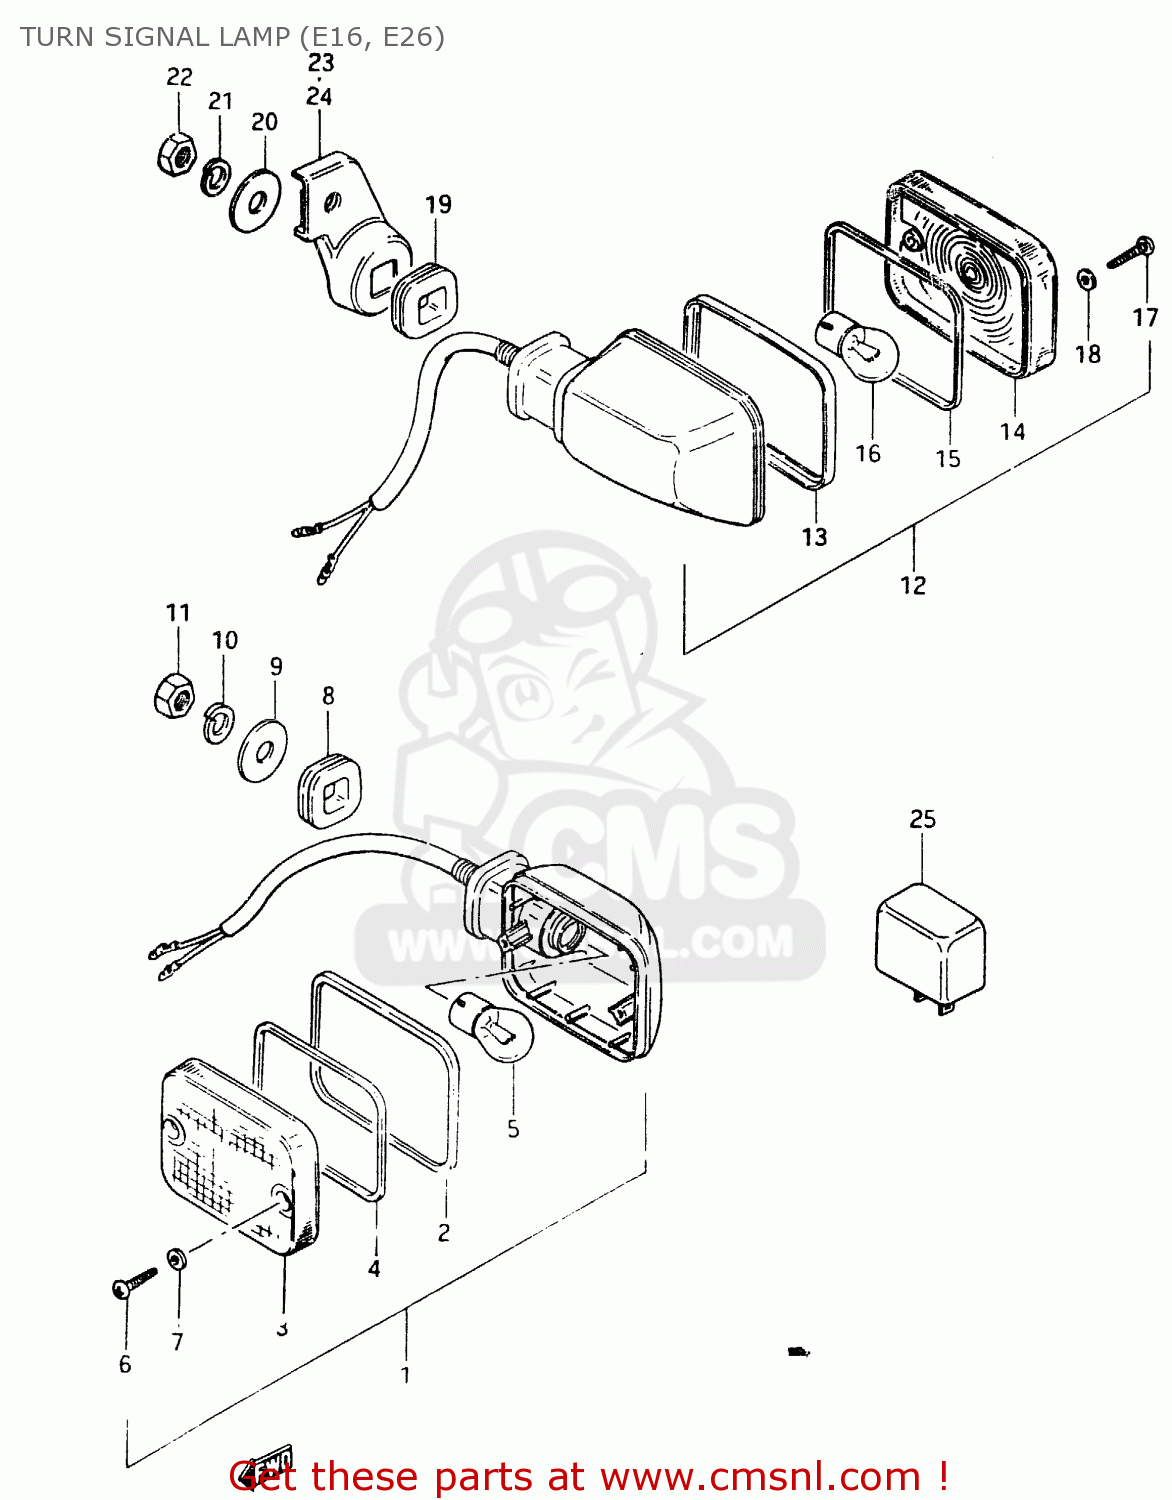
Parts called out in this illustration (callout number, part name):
1	LAMP ASSY,FR T
2	RIM
3	LENS
4	GASKET (NAS)
5	BULB(12V21W)
6	SCREW
7	GASKET (NAS)
8	CUSHION
9	WASHER (10.5X30X2.3)
10	LOCK WASHER
11	NUT
12	LAMP ASSY,RR T
13	RIM
14	LENS
15	GASKET (NAS)
16	BULB(12V21W)
17	SCREW
18	GASKET (NAS)
19	CUSHION
20	WASHER (10.5X30X2.3)
21	LOCK WASHER
22	NUT
23	BRACKET,REAR TURN SIGNAL
24	BRACKET,REAR TURN SIGNAL
25	RELAY,TURN SIGNAL
